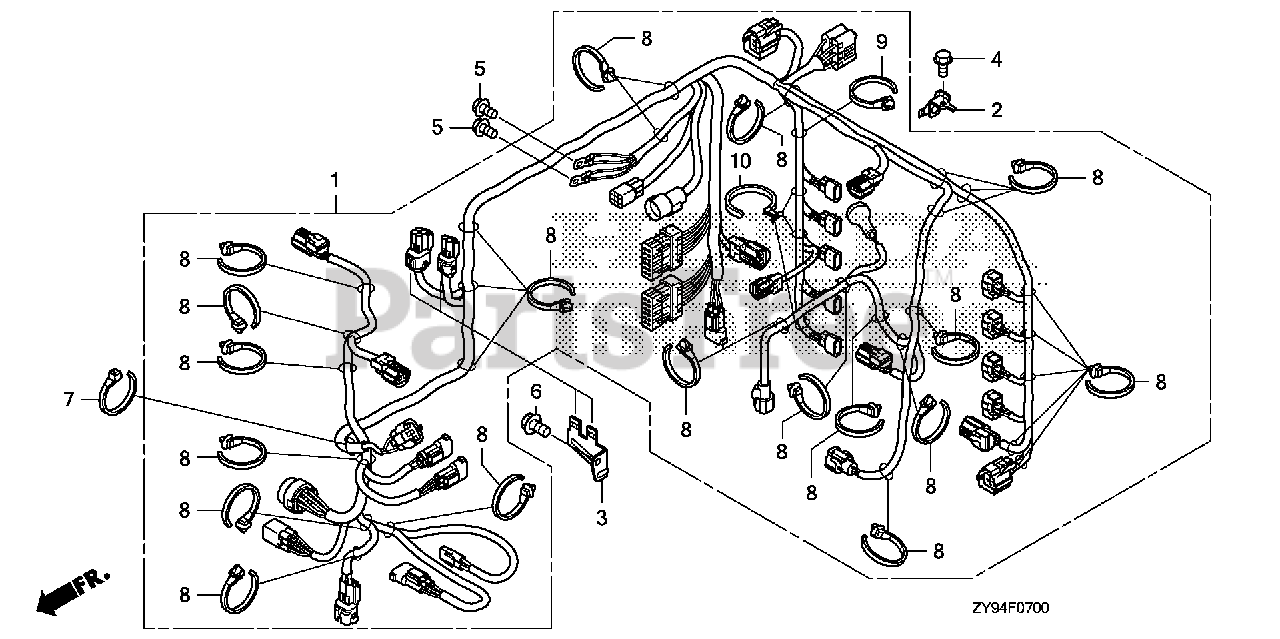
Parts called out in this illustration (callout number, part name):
1	WIRE HARNESS ASSY., MAIN
2	BRACKET A, CONNECTOR
3	BRACKET C, CONNECTOR
4	BOLT, FLANGE (6X14) (CT200)
5	BOLT, FLANGE (6X12)
6	BOLT, FLANGE (6X10)
7	BAND, WIRE HARNESS
8	CLIP, HARNESS BAND (145MM) (BLACK)
9	CLIP, HARNESS BAND (151MM) (BROWN)
10	STRAP, HARNESS (30) (107.5MM) (BLACK)
